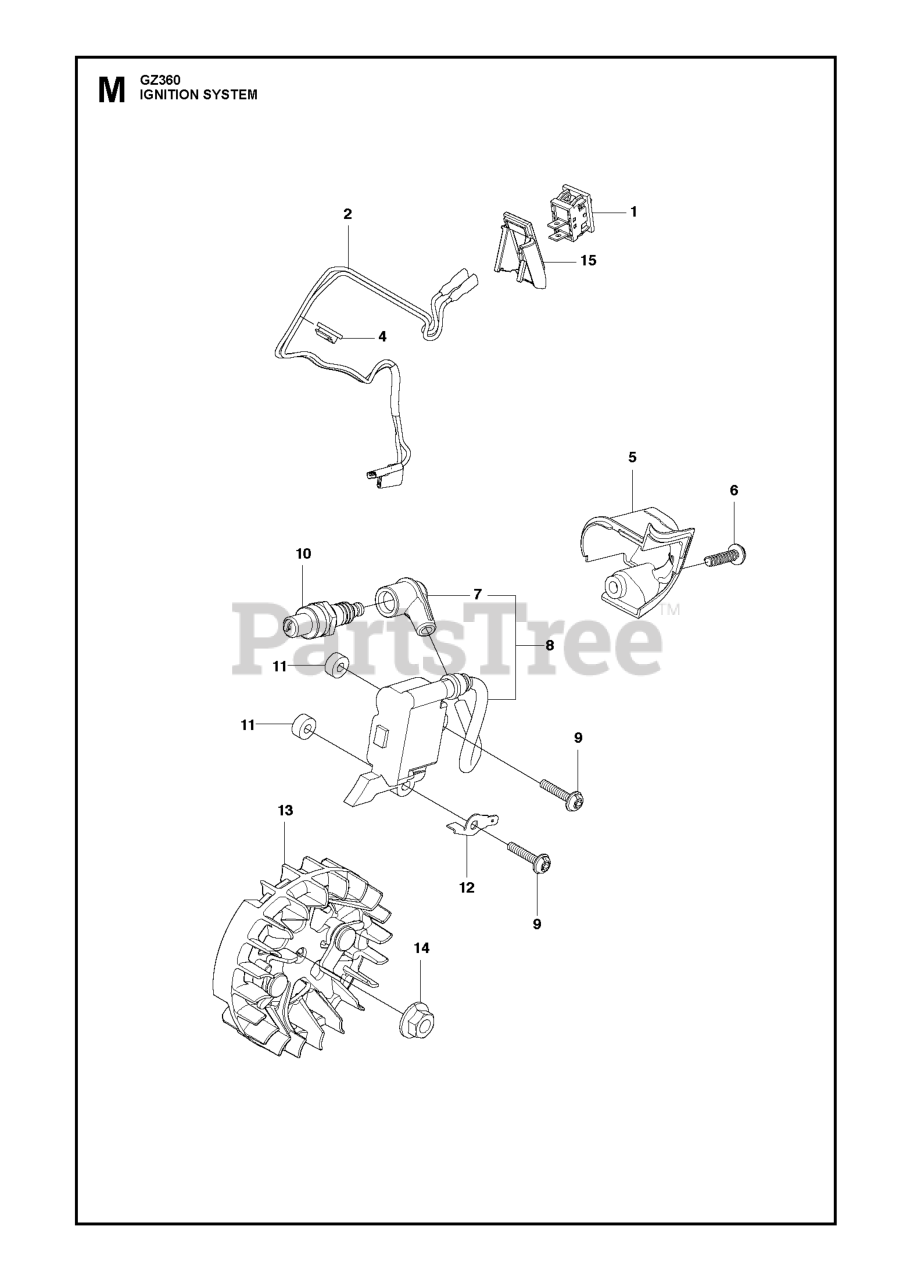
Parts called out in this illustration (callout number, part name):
2	WIRING ASSY
5	COVER SPARK PLUG BLACK
8	IGNITION COIL ASSY
9	BOLT M4X20
10	SPARK PLUG
12	TERMINAL
13	FLYWHEEL ASSY
14	NUT
15	BRACKET SWITCH GZ3500L
